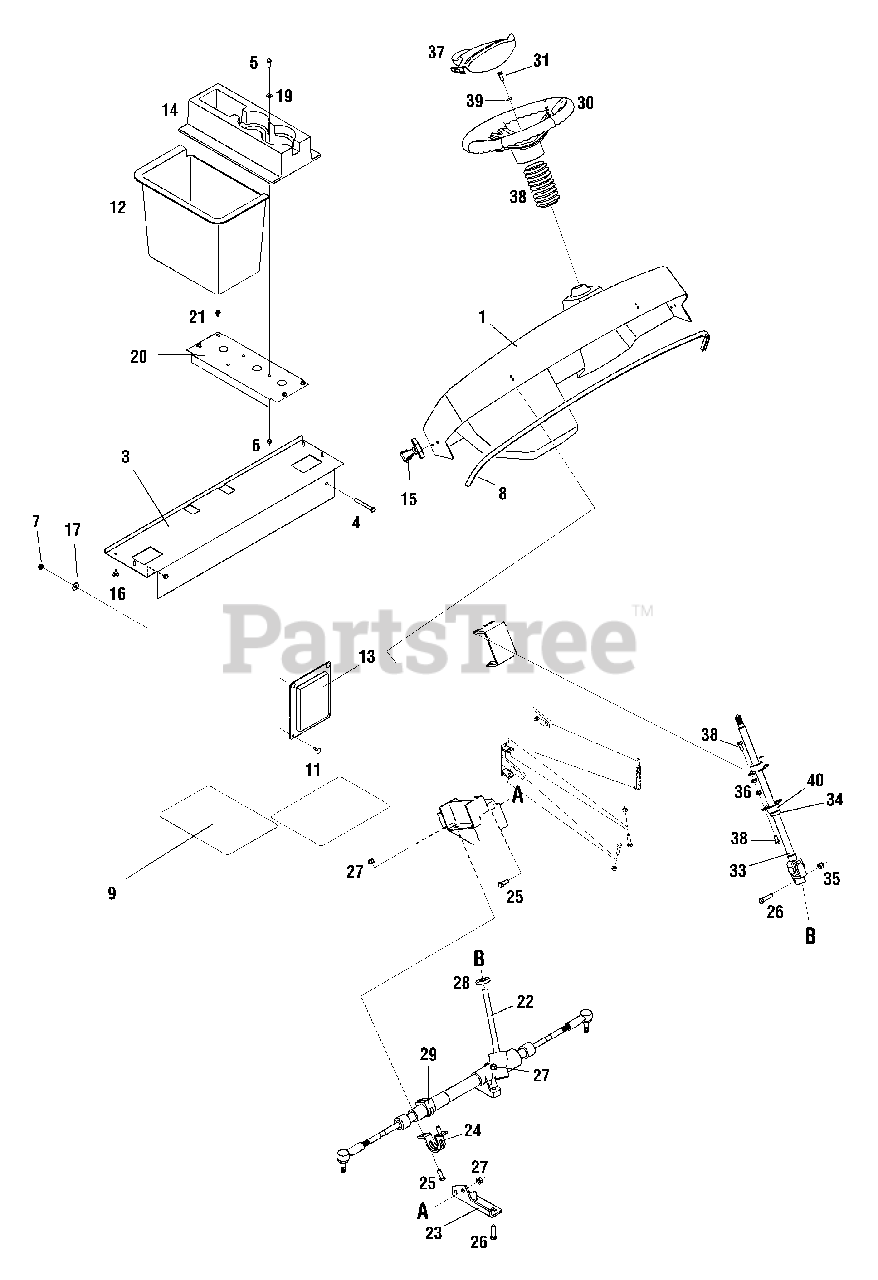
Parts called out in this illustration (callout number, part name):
1	Dash Assembly
2	Hood Mounting Plate
5	Hex Screw, 1/4-20 x .75, Gr5
6	Hex Lock Nut, Nylon, 1/4-20
7	Hex Lock Nut, Nylon, 5/16-18
8	Trim, Bulb Seal, 1/4
9	Foot Pad, Abrasive
10	Rivet, Pop, .187
11	Rivet, Pop, .188
12	Container, Bulkhead
13	Panel, Shift Cover
14	Console, Cup Holder
15	Handle, Latch
16	Bumper, Rubber
17	Washer, Flat, .349 x .879 x .063
18	Washer, Flat, .194 x .62 x .063
19	Washer, Flat, .25 x .630 x .0515
22	Gear Assembly, Steering
25	Hex Screw, 3/8-16, 1.00, Gr5
26	Hex Screw, 3/8-16, 1.50, Gr5
27	Nut, Flange Lock, 3/8-16
28	Grommet, Steering Shaft
29	Bushing, Rubber
30	Wheel, Steering
31	Hex Screw, 5/16-18, .75, Gr5, Patch
32	Hex Screw, 5/16-18, .75, Gr5
33	Shaft, Steering, 5/8 Spline
34	Collar, .75
35	Nut, Hex Lock Nylon, 3/8-16
36	Nut, Flange Lock, 5/16-18
37	Cover, Steering Wheel
38	Bellow, Steering, 4.75 Lg
39	Washer, Flat, .344 x .688 x .065
40	Bearing, Flange, .75 ID, Self-Aligning
